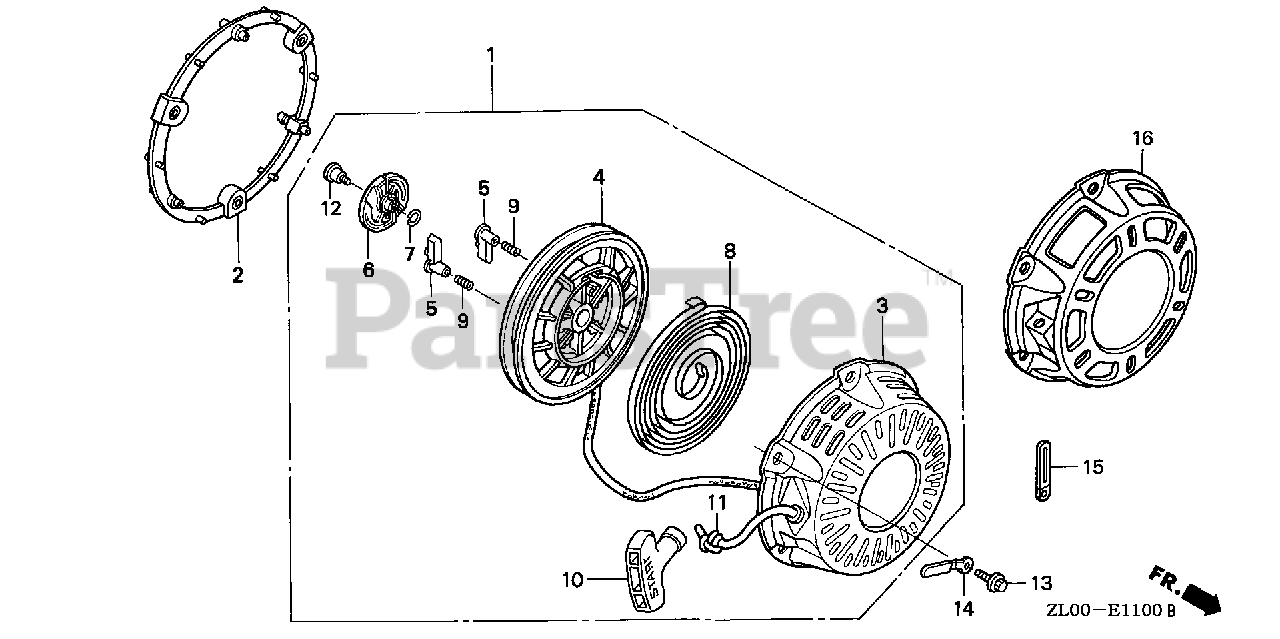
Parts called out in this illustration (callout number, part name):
1	STARTER ASSY., RECOIL *R280* (POWER RED)
1	STARTER ASSY., RECOIL *NH1* (BLACK)
2	SPACER, RECOIL STARTER MOUNTING *NH1* (BLACK)
2	SPACER, RECOIL STARTER MOUNTING *R280R* (POWER RED)
2	SPACER, RECOIL STARTER MOUNTING *R280* (POWER RED)
3	CASE, RECOIL STARTER *R280* (POWER RED)
3	CASE, RECOIL STARTER *NH1* (BLACK)
4	REEL, RECOIL STARTER (NATURAL)
5	RATCHET, STARTER
6	GUIDE, RATCHET
7	SPRING, FRICTION
8	SPRING, RECOIL STARTER
9	SPRING, RETURN
10	GRIP, STARTER
10	KNOB, RECOIL STARTER
11	ROPE, RECOIL STARTER
12	SCREW, SETTING
13	BOLT, FLANGE (6X18)
